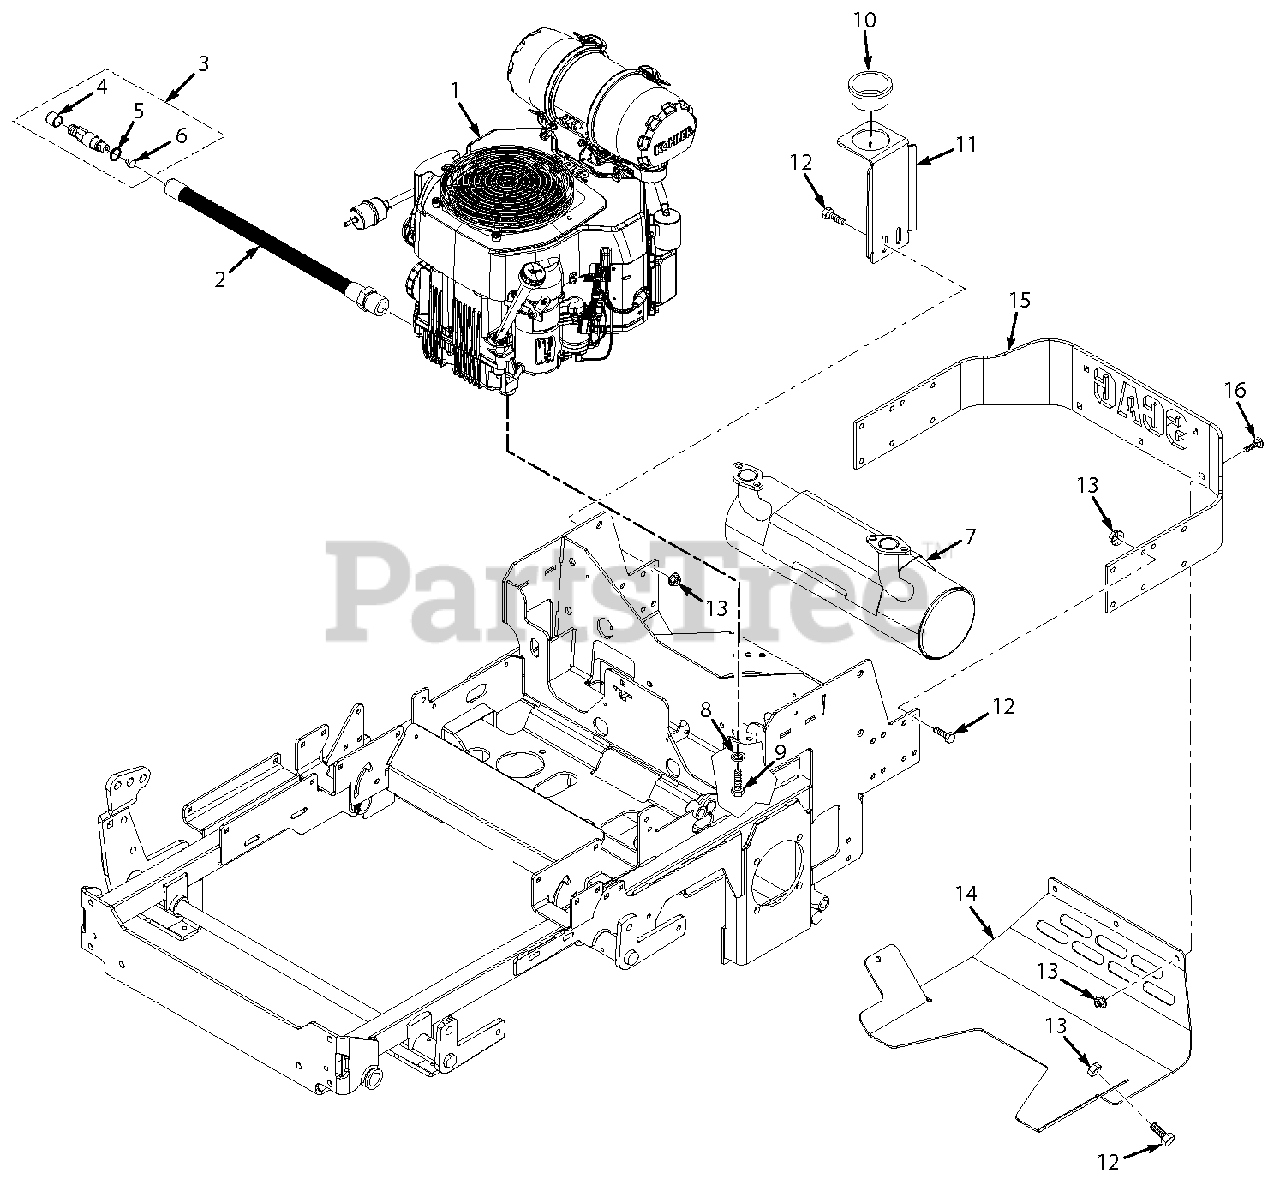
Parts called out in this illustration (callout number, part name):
1	Engine, Kawasaki 22FX
1	Engine, Kawasaki 23FX
1	Engine, Kohler 23CV
1	Engine, Kohler 25CV-EFI
1	Engine, Kohler 29CV-EFI
2	Hose, Oil Drain - Kawasaki FX
2	Hose, Oil Drain - Kohler CV & CV-EFI
3	Valve Assembly, Oil Drain
5	O-Ring
7	Muffler, Kawasaki FX
7	Muffler, Kohler 23CV
7	Muffler, Kohler 25CV-EFI
7	Muffler, Kohler 29CV-EFI
8	Lockwasher, 3/8" Spring, Kawasaki FX
9	Bolt, Hex Head 3/8-16 x 1-1/4", Kawasaki FX
9	Bolt, Hex Head 3/8-16 x 1-1/4" Self Tap, Kohler CV & CV-EFI
10	Bushing, Thick Panel Snap
11	Bracket, Oil Drain Hose
12	Bolt, Hex Head 3/8-16 x 1"
13	Nut, Serrated Flange 3/8-16
14	Plate, Skid
15	Bumper, Rear
16	Bolt, Carriage 3/8-16 x 1"
